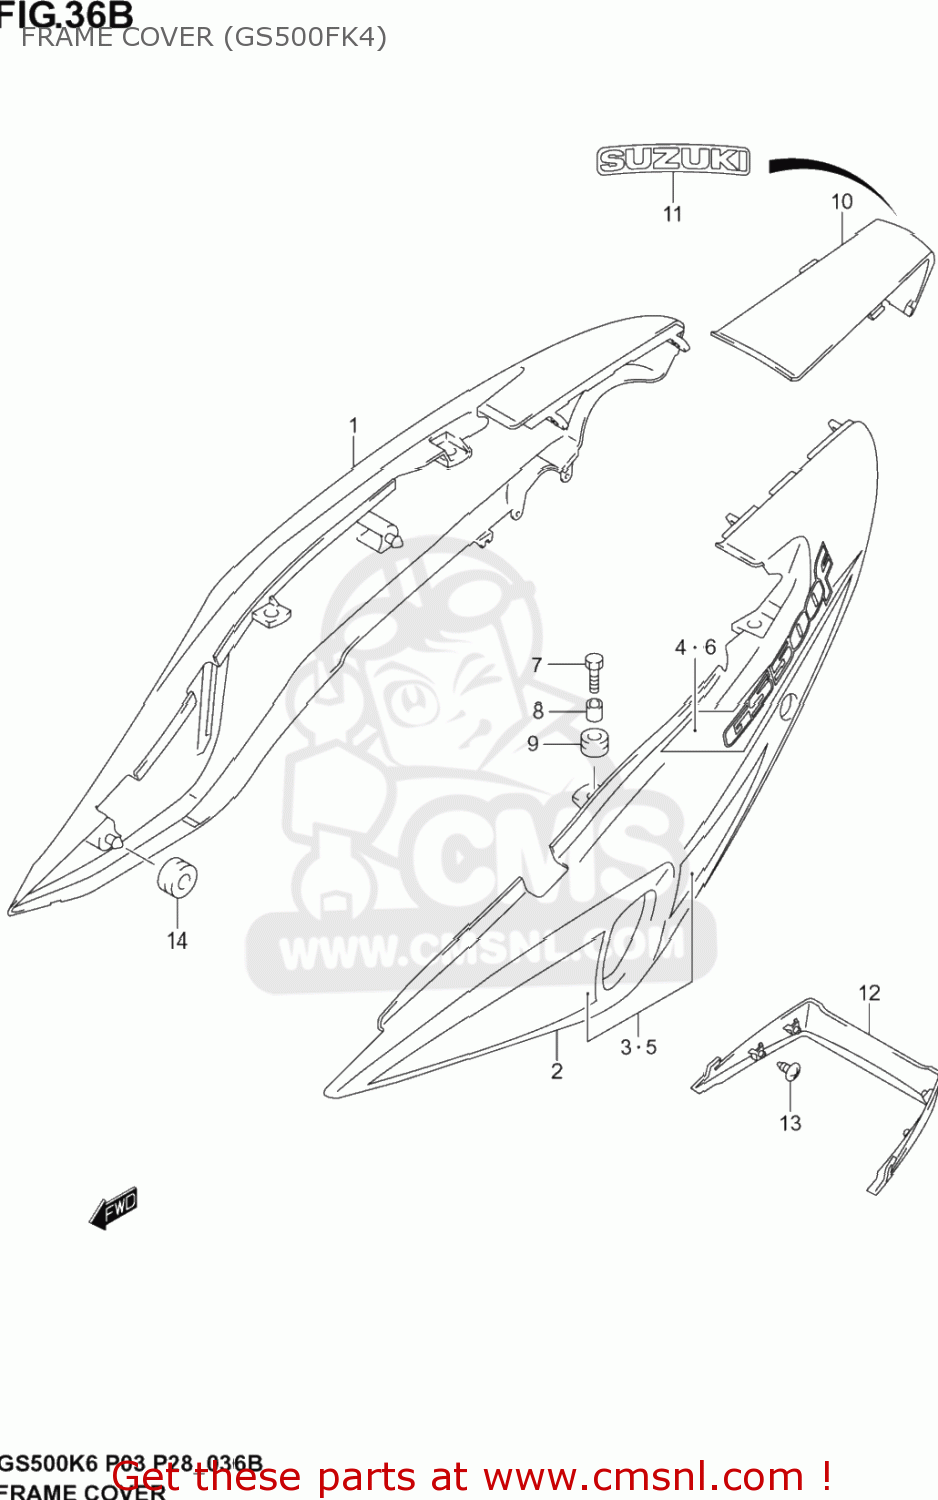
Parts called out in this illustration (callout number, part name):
1	COVER,FRAME RH
2	TAPE SET
3	TAPE SET FRONT
4	TAPE,REAR FRAM
5	TAPE SET, FRON
6	TAPE, REARFRAM
7	BOLT(6X20)
8	SPACER(6.5X9X9)
9	CUSHION
10	COVER, CENTER
11	EMBLEM (SILVER
12	COVER LOWER
13	SCREW
14	CUSHION
